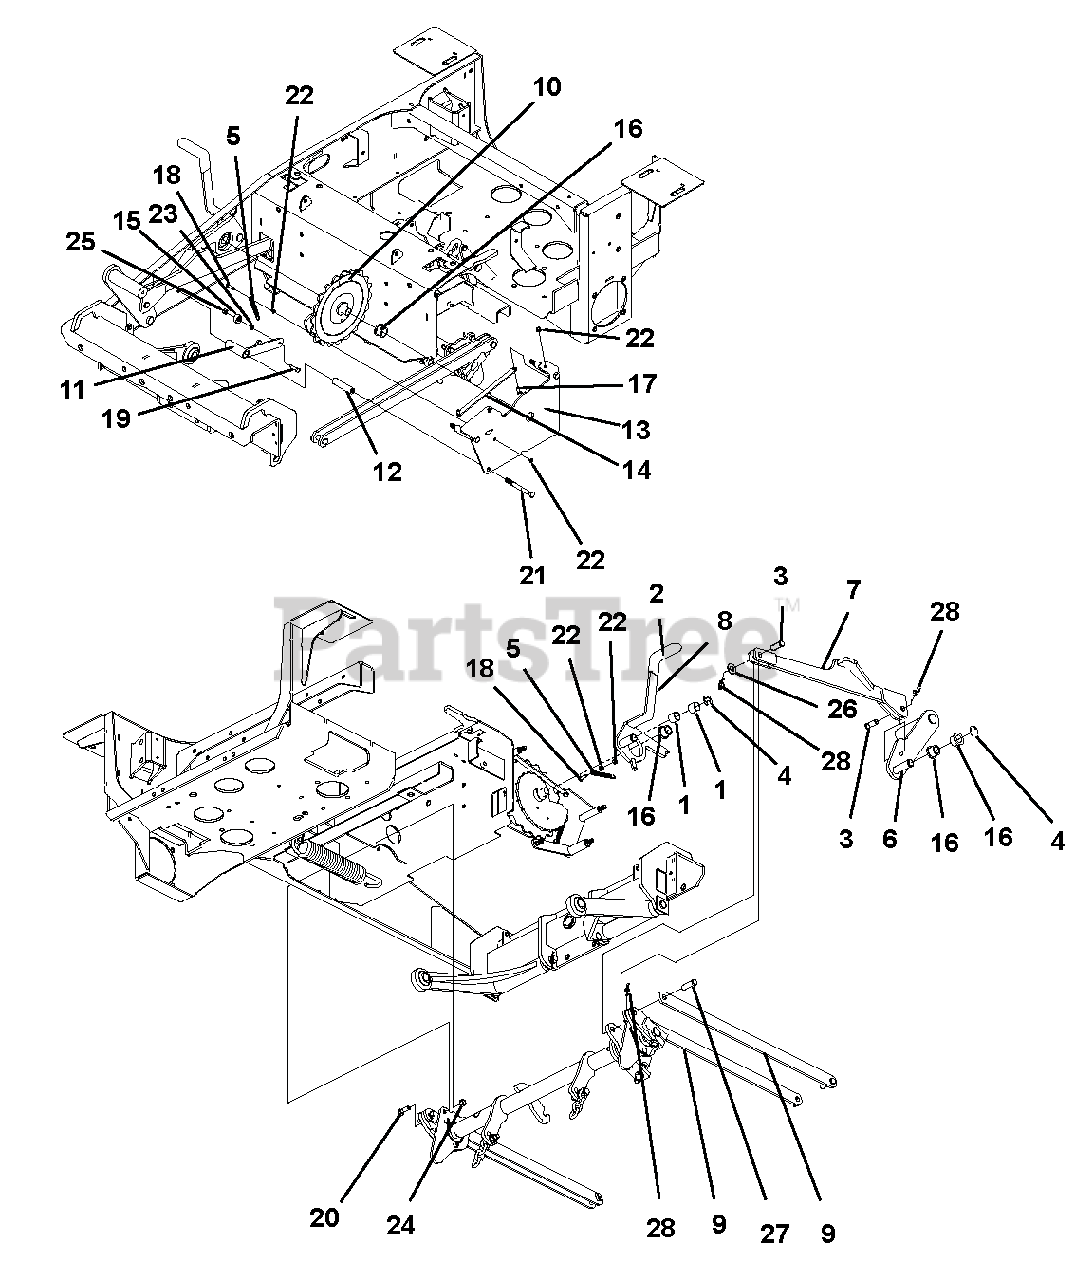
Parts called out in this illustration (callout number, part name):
1	BRG, SLV .753X.878X.750
2	GRIP, RUBBER LEVER
3	PIN,CLEV .50X1.25X1.02 YWZC
4	E-RING, .750 X .050 Y
5	SPRING, EXT .375X.055X2.25 Y
6	WLDT, FOOT ARM
7	WLDT, FOOT CONNECTOR
8	WLDT, TRANSPORTATION LOCK
9	PLATE, CONNECTOR LINK
10	ASSY, CAM CONTROL W/DECALS S/O
11	WLDT, ARM
12	TUBE, RD .625 X .120 X 2.53 Y
13	PLATE, HOC INDICATOR
14	PLATE, FINGER GUARD
15	BRG, BAL .250X.688X.313
16	BUSHING, .750 X 1.00 X .750
17	@BLT-HEX .25-20X.50 GR5 YWZC
18	@BLT-HEX .25-20X.75 GR5 YWZC
19	@BLT-HEX .25-20X1.00 GR5 YWZC
20	@BLT-HEX .38-16X1.00 GR5 YWZC
21	@BLT-HEX .38-16X3.50 GR5 YWZC
22	@NUT-HEX .25-20 YWZC
23	WSHR-FL-STL M6 7X13X1.5 YWZC
24	NUT-LK-FLG .375-16 PL
25	@NUT-LK-NYL .250-20 YWZC
26	@WSHR-FL-STL.531X1.06X.095YWZC
27	PIN-CLEV .50X1.50X1.27 YWZC
28	RING, RUE .500 X .062 X 1.420
